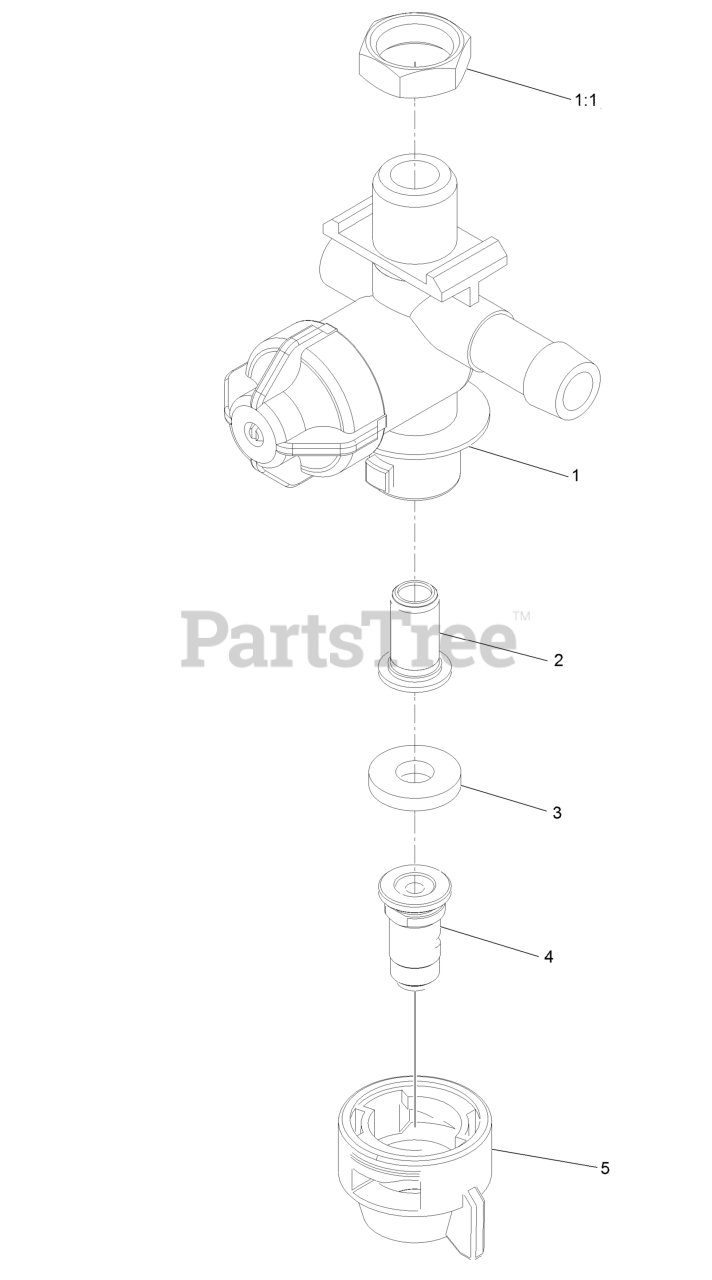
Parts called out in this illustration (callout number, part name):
1	LH Nozzle Body ASM
1:1	Nut-Nylon
2	Strainer-Tip
3	Gasket-Seal
4	Nozzle-Spray, White
5	Cap-Nozzle
99	Nozzle-Spray, Blue
99	Nozzle-Spray, Brown
99	Nozzle-Spray, Gray
99	Nozzle-Spray, Red
